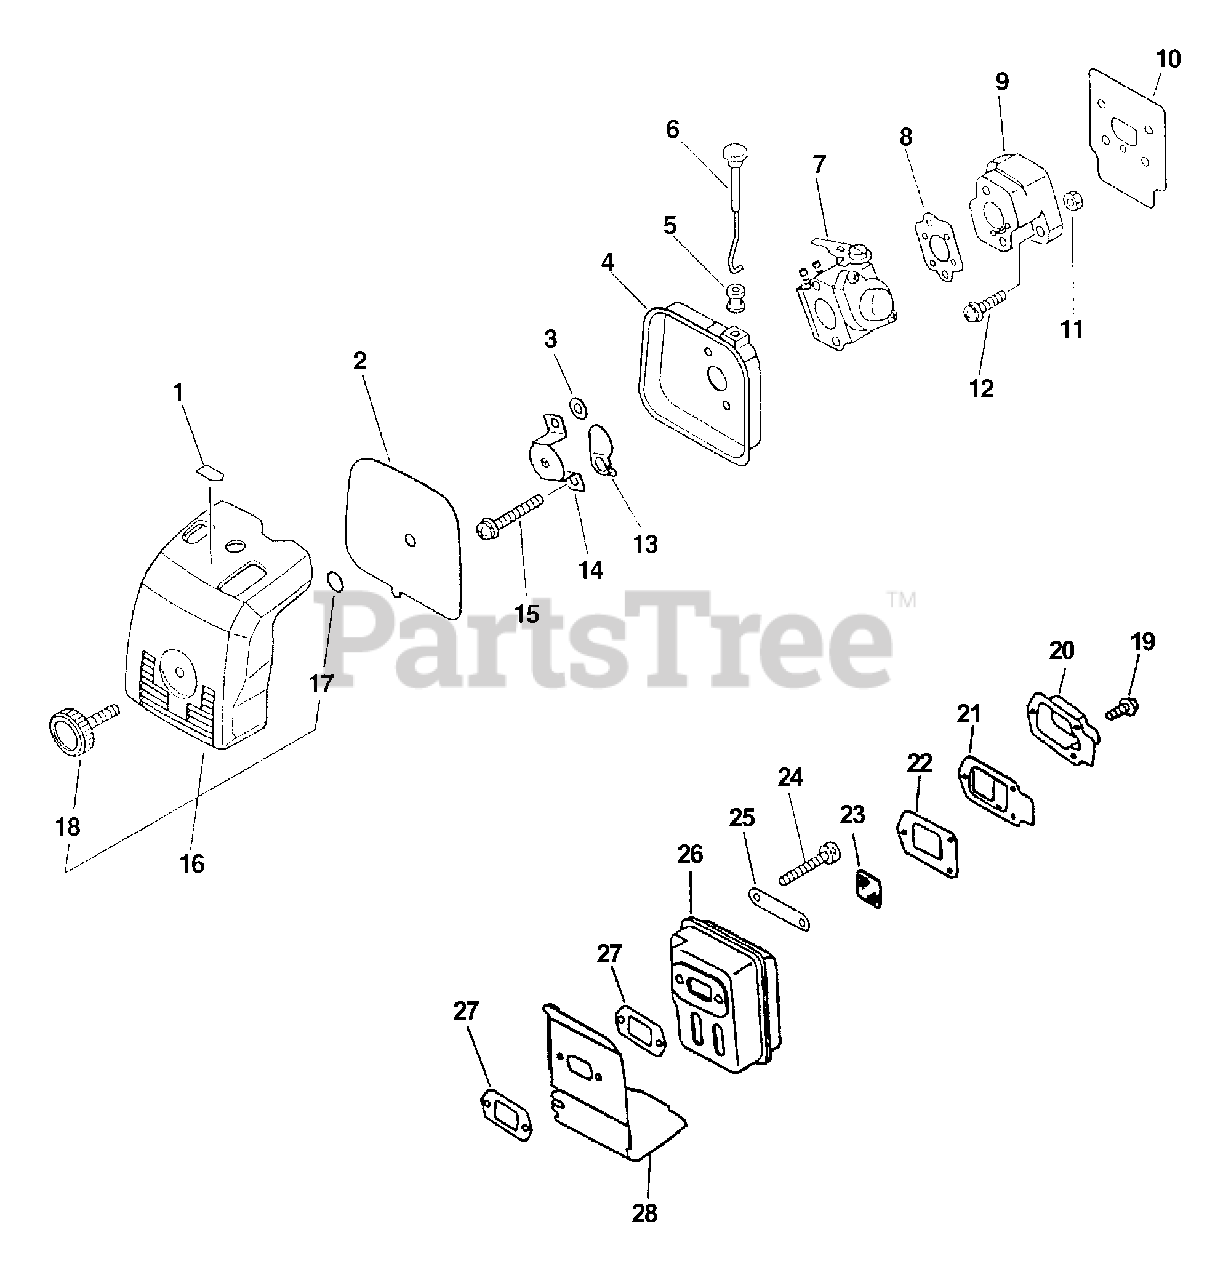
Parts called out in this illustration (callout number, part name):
1	LABEL, CHOKE
2	FILTER, HEAVY-DUTY AIR
3	WASHER 5.2×8×0.8T
4	CASE, AIR FILTER
5	GROMMET, CHOKE
6	ROD, CHOKE
7	CARBURETOR - WT-424C
8	GASKET, CARBURETOR
9	INSULATOR, INTAKE
10	HEAT SHIELD, INTAKE
11	NUT M5
12	SCREW 5×20
13	SHUTTER, CHOKE
14	PLATE, PREVENT
15	SCREW 5×57
16	AIR FILTER COVER ASSY
17	O-RING 3
18	THUMBSCREW
19	SCREW 4×10
20	GUIDE, EXHAUST
21	OUTLET, EXHAUST
22	GASKET, EXHAUST
23	SCREEN, SPARK ARRESTER
24	BOLT 5×55
27	GASKET, EXHAUST
28	HEAT SHIELD, EXHAUST
29	GASKET KIT
